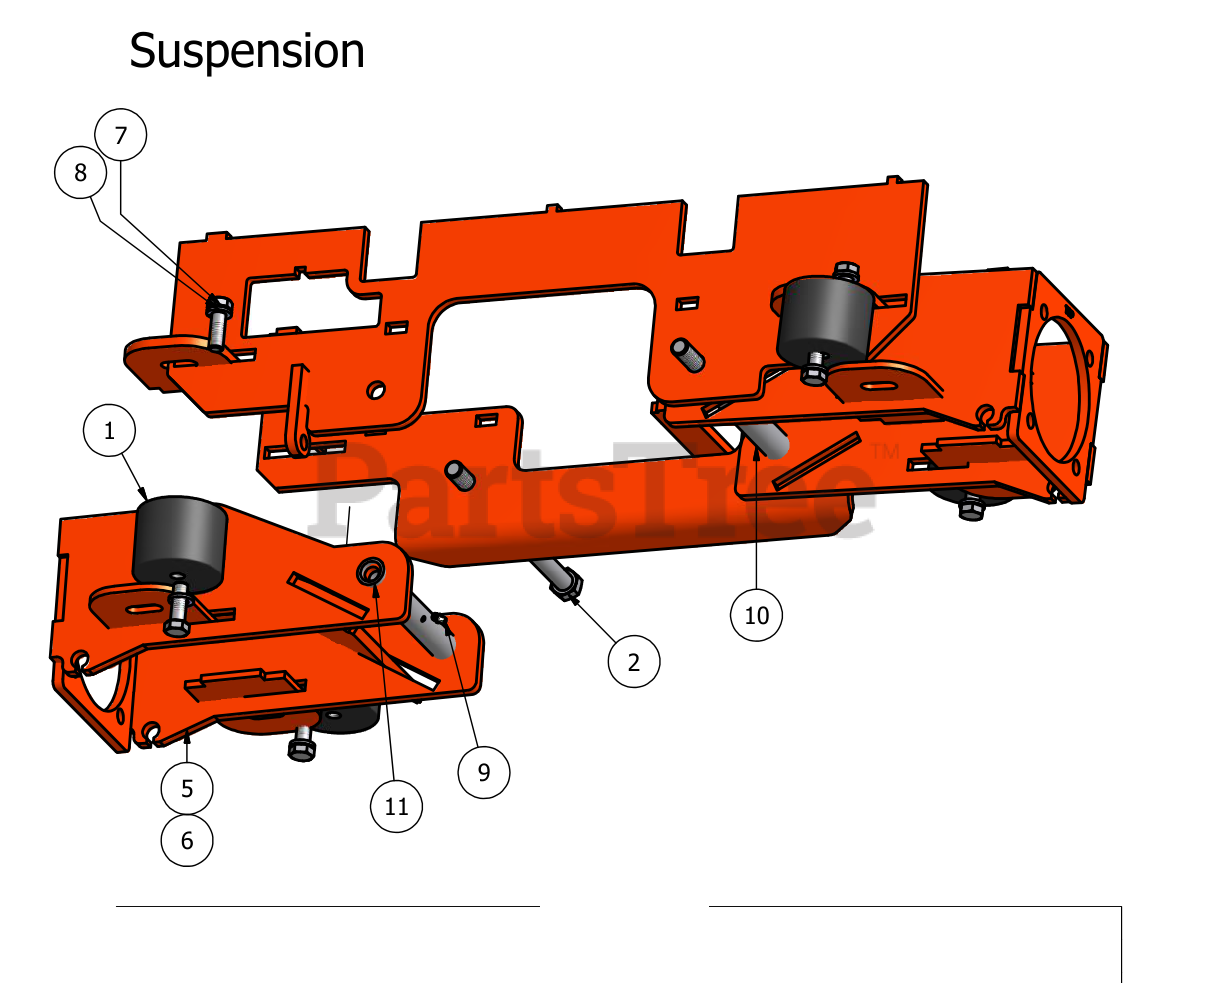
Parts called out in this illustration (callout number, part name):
1	Vibration Mount
2	5/8" x 10" Hex Bolt (Grade 8)
3	5/8" Nylock 1/2 Jam
5	60" Inner Suspension Cage
6	72" Inner Suspension Cage
7	1/2" x 1 1/2" Hex Bolt
8	1/2" Lock Washer
9	Grease Fittting (Drive-In)
10	Shoulder Spacer
11	3/4" Brass Bushing
